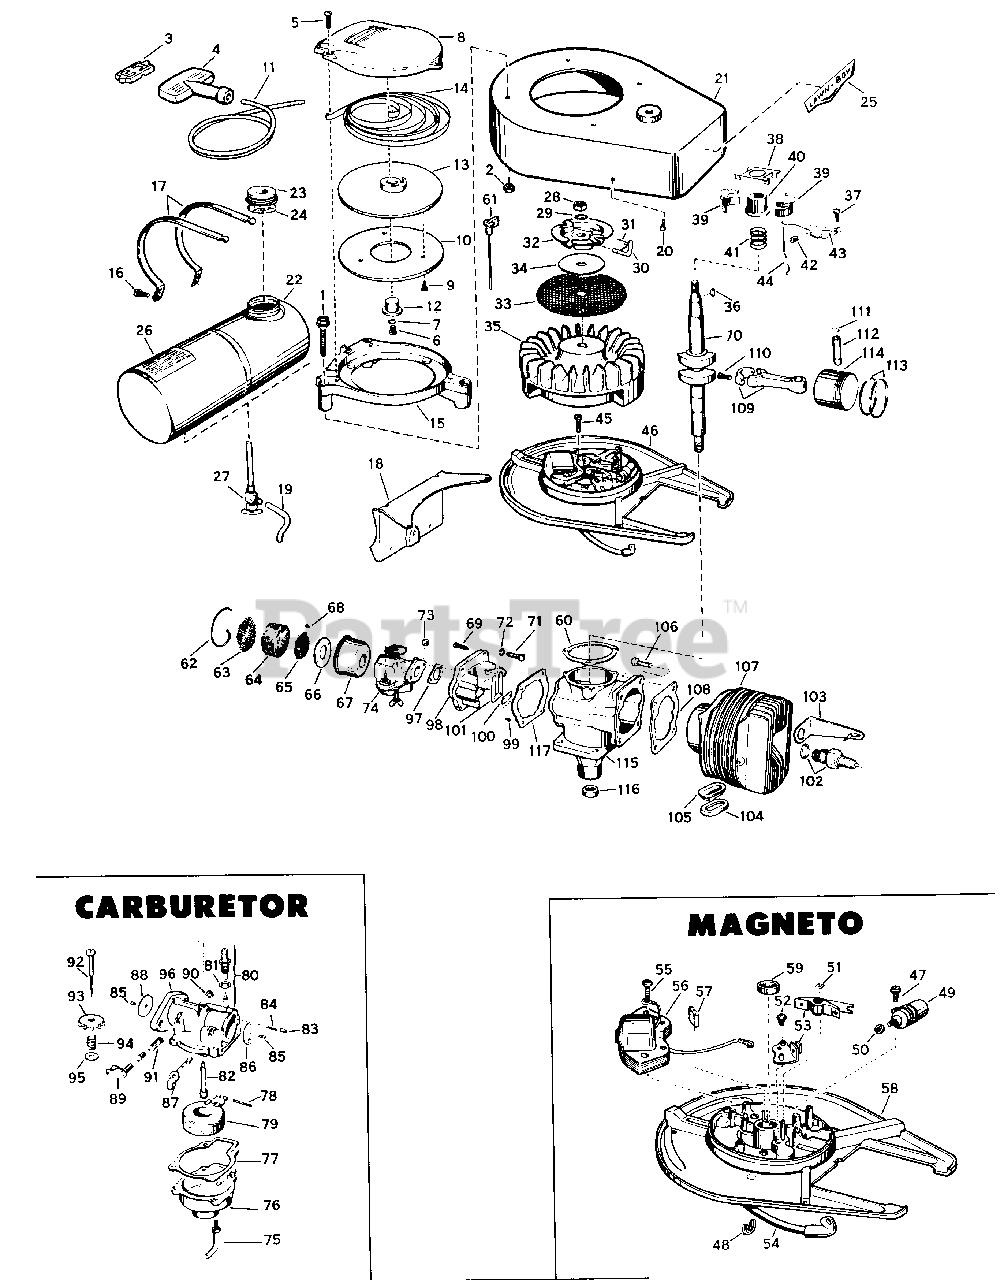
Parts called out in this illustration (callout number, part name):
1	Screw-Starter to Shroud
2	Nut-Starter to Shroud
3	Anchor-Rope
4	Handle-Starter
5	Screw-Starter Cap to Base
6	Screw-Pulley to Cap
7	Washer-Lock, Pulley to Cap
8	Cap-Starter
9	Screw-Pulley Plate
10	Plate-Pulley
11	Rope-Starter
12	Bearing-Pulley
13	Pulley-Rewind
14	Spring-Recoil
15	Base-Starter
16	Screw-Tank Strap
17	Strap-Gas Tank
18	Bracket-Gas Tank
19	Line-Gas
20	Screw-Shroud to Arm. Plate
22	Gas Tank Assembly
23	Cap and Gasket Assembly
24	Gasket-Tank Cap
25	Decal-"Lawn-Boy"
26	Decal-Instruction
27	Shut-off Valve and Screen Assy.
28	Nut-Flywheel
29	Washer-Lock, Flywheel
30	Pin-Starter
31	Spring-Starter
32	Pulley-Flywheel
33	Screen-Flywheel
34	Washer-Flywheel
35	Flywheel Assembly
36	Key-Woodruff, Flywheel
37	Screw-Governor
38	Yoke-Governor
39	Weight-Governor
40	Collar-Governor
41	Spring-Governor
42	Block-Wear, Governor
43	Governor Lever and Wear Block Assembly
44	Rod-Governor
45	Screw-Crankcase to Armature Plate
46	Armature Plate Assembly
47	Screw-Condenser and Clamp Mounting
48	Clamp-High Tension Lead
49	Condenser Assembly
50	Nut-Condenser Terminal
51	Clip-Spring, Breaker Post
52	Screw-Breaker Base
53	Breaker Base and Arm Assy.
54	High Tension Lead Assy.
55	Screw-Lamination Mtg.
56	Coil and Lamination Assy.
57	Wick-Oiler
58	Armature Plate, Post, Bearing and Oil Seal Assy.
59	Seal-Oil
60	Gasket-Crankcase to Arm. Plate, .005 in.
60	Gasket-Crankcase to Arm. Plate, .010 in.
61	Choke Knob Assembly
62	Clip-Air Filter
63	Screen-Air Filter (Large)
64	Element-Air Filter
65	Screen-Air Filter (Small)
66	Plate-Back-up, Filter Cup
67	Cup-Air Filter
68	Screw-Air Filter
69	Screw-Reed Plate to Crankcase
70	Crankshaft
71	Screw-Reed Plate to Carb.
72	Washer-Reed Plate to Carb. Screw
73	Nut-Stop, Reed Plate to Carb. Screw
74	Carburetor Assembly
75	Screw-Wing
76	Float Chamber
77	Gasket-Carb. Body to Float Chamber
78	Pin-Float Arm Hinge
79	Float and Arm Assembly
80	Float Valve, Seat and Washer Assembly
81	Washer-Float Valve Seat
82	Nozzle
83	Plug-Choke, Friction
84	Spring-Choke, Friction
85	Screw-Choke and Throttle Disc
86	Disc-Choke
87	Choke Shaft and Lever Assy.
88	Disc-Throttle
89	Throttle Shaft and Ring Assy.
90	Grip-Ring
91	Spring-Throttle Shaft
92	Needle Assembly
93	Knob-Needle Valve
94	Spring-Needle Adjustment
95	Washer-Needle Adjustment
96	Carburetor Body
97	Gasket-Carburetor
98	Reed Plate Assembly
99	Screw-Reed to Reed Plate
100	Plate-Back-up, Reed
102	Spark Plug and Gasket
103	Lever-Stop
104	Gasket-Exhaust
105	Sleeve-Exhaust Gasket
106	Screw-Cylinder to Crankcase
107	Cylinder and Sleeve Assembly
108	Gasket-Cylinder to Crankcase
109	Connecting Rod Assembly
110	Screw-Connecting Rod
111	Ring-Spring
112	Pin-Wrist
113	Ring-Piston
115	Crankcase, Oil Seal and Reed Plate Gasket Assembly
116	Seal-Oil
117	Gasket-Reed Plate to Crankcase
